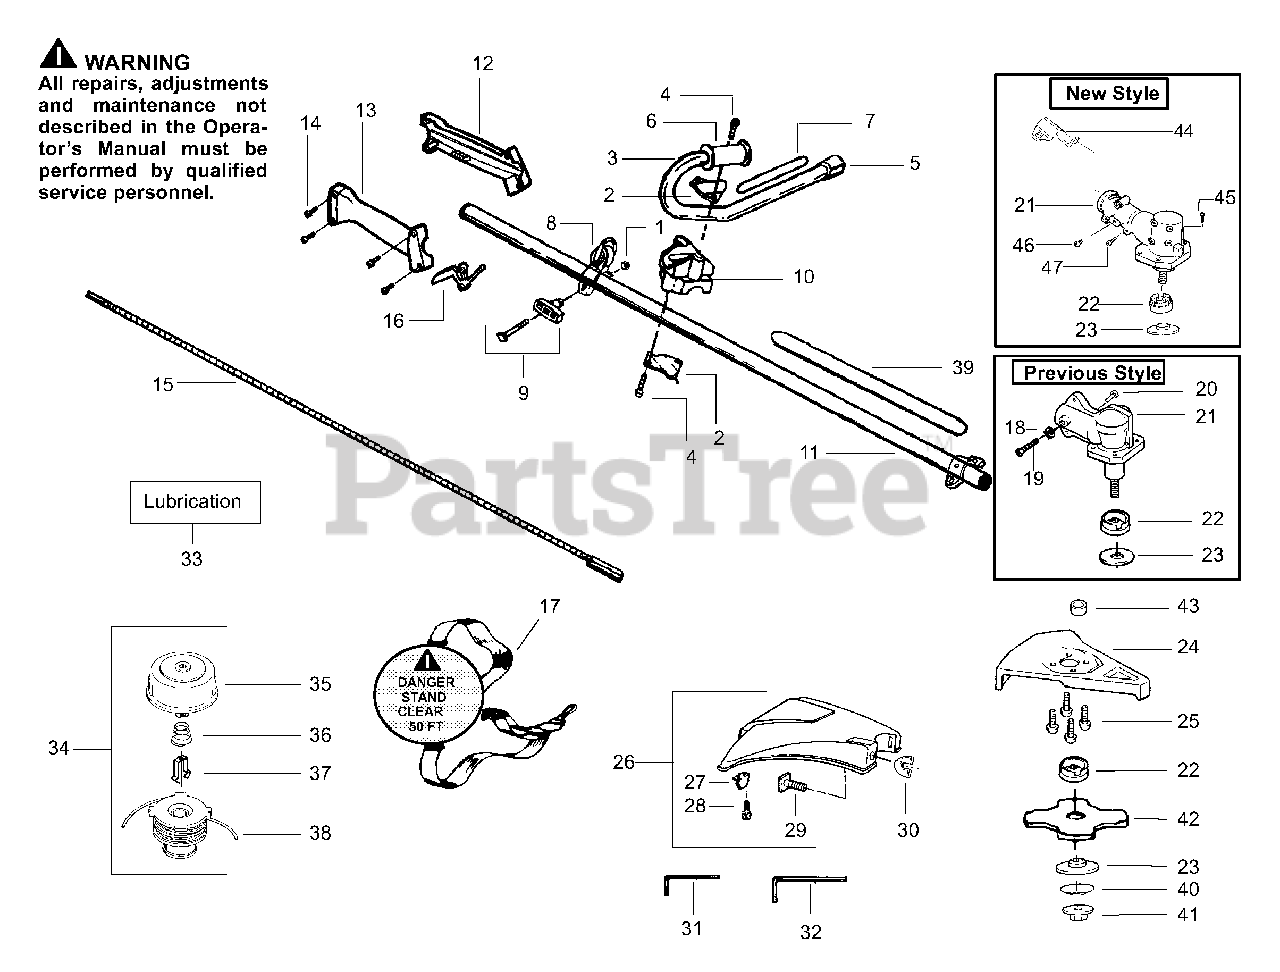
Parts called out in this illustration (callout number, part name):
2	Handlebar Bracket
3	Handlebar Ass'y.
5	Handlebar Cap
6	Handlebar Grip
7	Handlebar Warning Decal
8	Harness Clamp Ass'y.
9	"T" Handle Assy.
10	Handlebar Clamp
11	Drive Shaft Housing
12	Throttle Hsg. Left
13	Throttle Hsg. Right
15	Shaft - Flex
16	Throttle Lever
17	Shoulder Strap
18	Lockwasher
20	Screw-Pinch Clamp
21	Gear Box Ass'y.
22	Dust Cup
23	Washer
24	Metal Shield Kit
26	Shield Kit Ass'y.
27	Line Limiter
28	Screw
30	Wingnut
31	Hex Wrench (5/32)
32	Hex Wrench (3/16)
33	Shaft Lubrication
34	Cutting Head Ass'y.
35	Hub Ass'y.
36	Spring-Return
37	Retainer-Spool
38	Spool w/Line
39	Decal Shaft Warning
40	Washer-Belleville
42	Weed Blade
43	Seal Sleeve
44	Bracket-Shield
